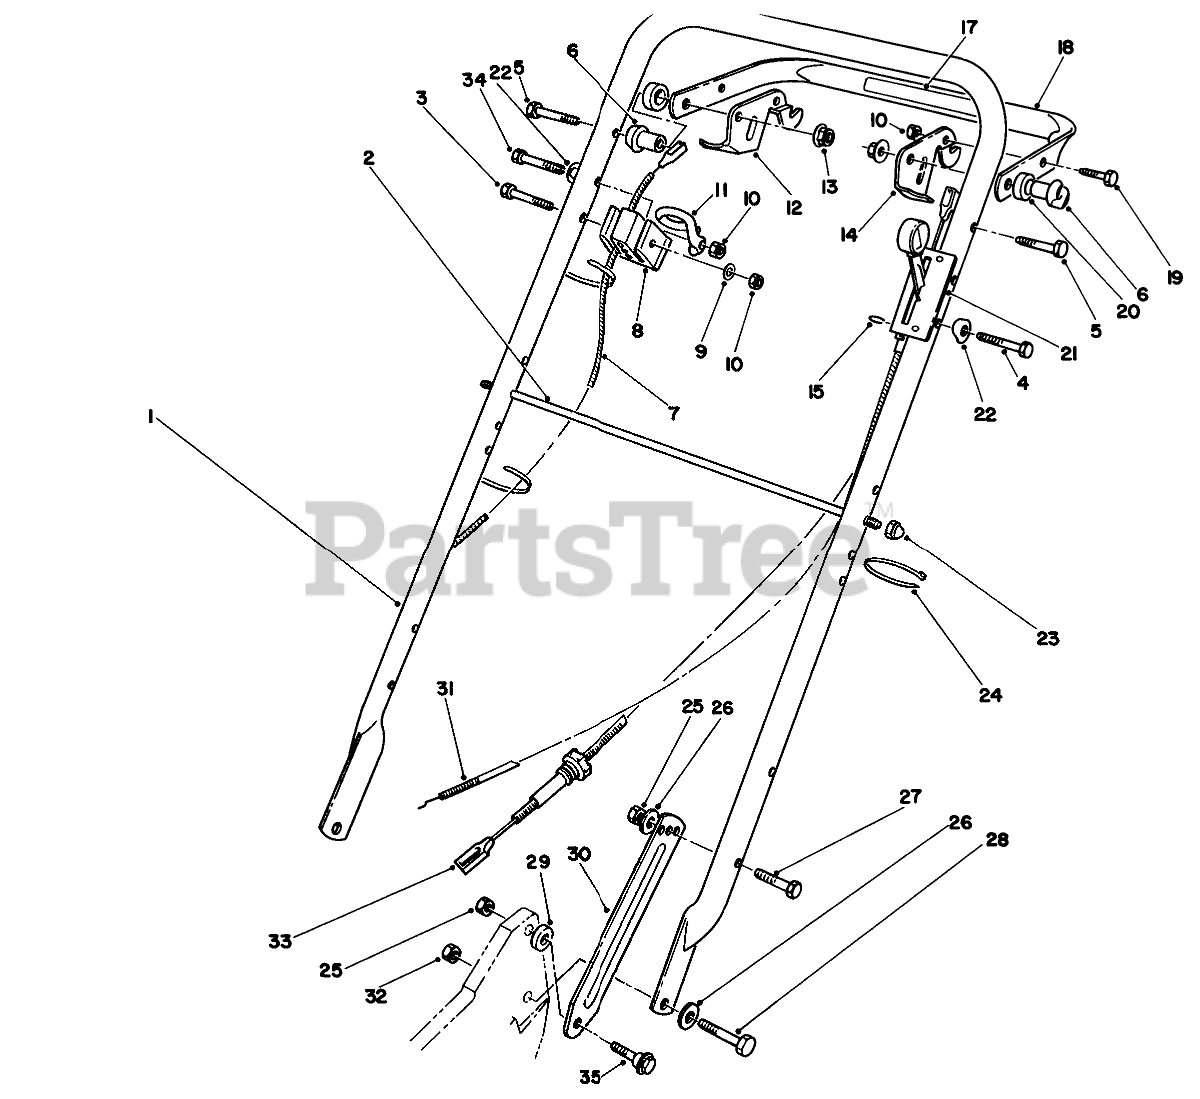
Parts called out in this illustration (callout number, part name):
1	Handle
2	ROD-SUPPORT, BAG
3	SCREW-HH
4	SCREW-HH
5	SCREW-HH
6	SPACER-SUPPORT
7	Cable-Brake
8	SUPPORT-CABLE
9	WASHER-FLAT
10	NUT-LOCK, NI
11	GUIDE-ROPE
12	LEVER-CONTROL
13	NUT-LOCK, NI
14	LEVER-CONTROL
15	E-RING
17	DECAL/TRACTION CONTROL
18	Bar-Control
19	SCREW-HH
20	SPACER-NYLON
21	CONTROL-THROTTLE
22	WASHER
23	NUT-CAP
24	TIE-CABLE
25	NUT-LOCK, NI
26	WASHER-BELLEVILLE
27	SCREW-HH
28	SCREW-HH
29	SPACER
30	Latch-Handle
31	CABLE-THROTTLE
32	NUT-LOCK, NI
33	CABLE-TRACTION
34	SCREW-HH
35	SCREW-SHOULDER
